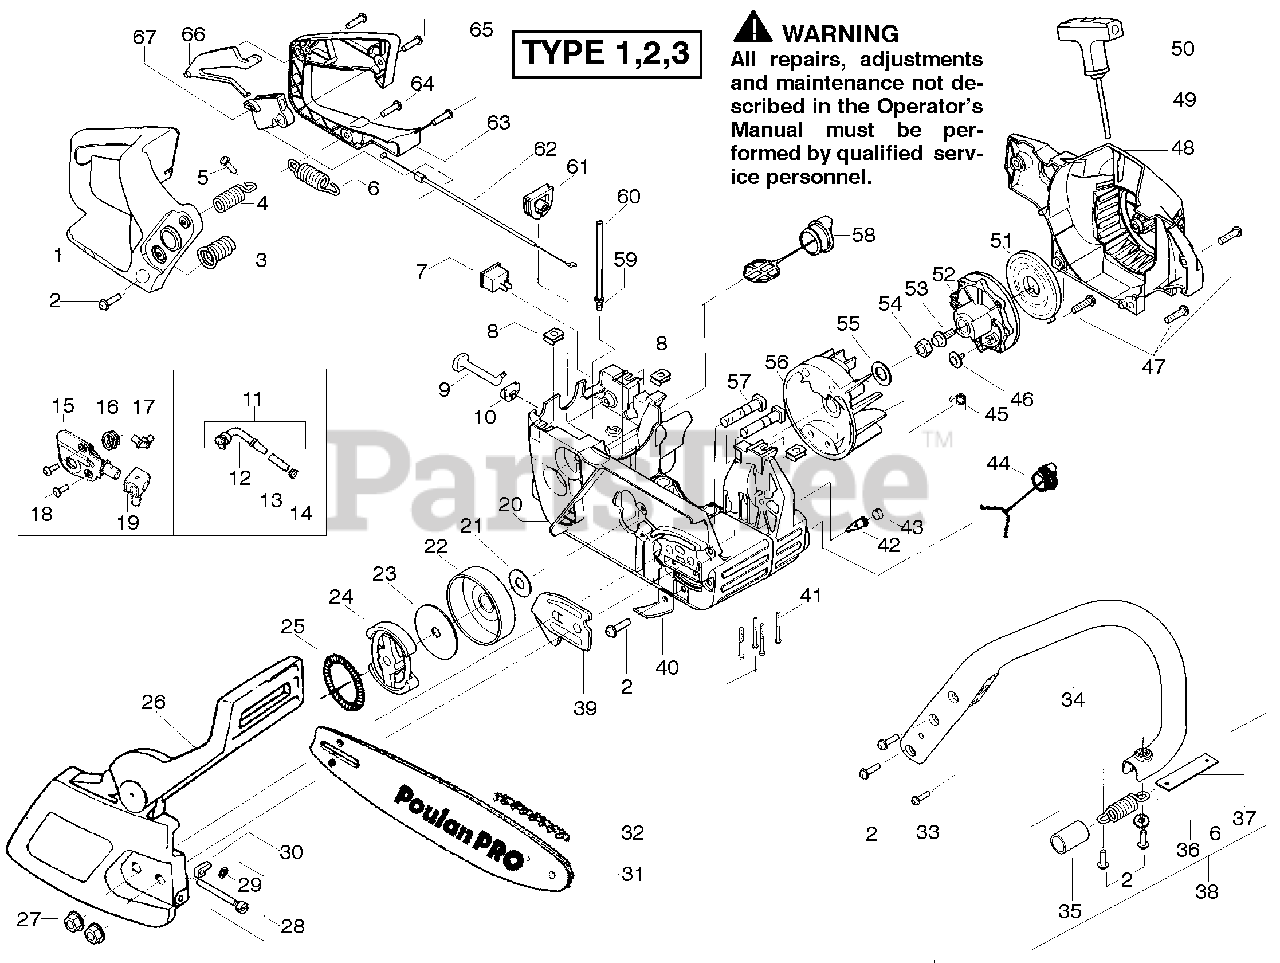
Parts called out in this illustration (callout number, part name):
1	Rear Handle
3	Isolator Ass'y. (Lower)
4	Isolator Kit (Upper)
6	Spring- Isolator
7	Switch Kit
8	Nut- "U" Type
9	Choke Knob
10	Grommet-Choke Knob
11	Oil Pick-up Ass'y
12	Pick-up Oiler
13	Oil Filter
14	Plug-Oil Filter
15	Oil Pump Kit
16	Gear-Worm Spring
17	Elbow-Oil Pickup
19	Seal Block
20	Chassis Ass'y.
21	Washer-Thrust
22	Clutch Drum Ass'y. w/Bearing
23	Washer - Clutch
24	Assy. Clutch
25	Spring-Clutch
26	Chain Brake Kit, Quick Adjust
26	Chain Brake Kit, Standard
27	Nut-Bar Mounting
28	Kit-Bar Adjust
29	Retainer-Bar Adjust
30	Pin-Bar Adjust
31	BAR, 16" Standard
31	BAR, 18" Standard
31	BAR, 18" Quick Adjust
31	BAR, 18" Quick Adj. pro lam
32	Chain, 16"
32	Chain, 18"
34	Front Handle
35	Sleeve-AV Spring
37	Limiter Strap
38	Assy.- Isolator
39	Plate-Bar Mounting
40	Chain Catcher
42	Check Valve
43	Plug-Bronze Vent
44	Assy.-Oil Cap
45	Spring-Starter Dog
48	Fan Housing
49	Kit - Rope
50	Handle-Starter
51	Spring-Recoil
52	Pulley-Starter
54	Nut- Flywheel
55	Washer- Flywheel
56	Flywheel, Walbro
56	Flywheel, Phelon
57	Bolt-Bar
58	Assy.-Fuel Cap
59	Fitting- fuel line
60	Kit-Fuel line (large)
61	Grommet-Cable
62	Cable - Throttle
63	Cover-Rear Handle
66	Throttle Lockout
67	Trigger-Throttle
